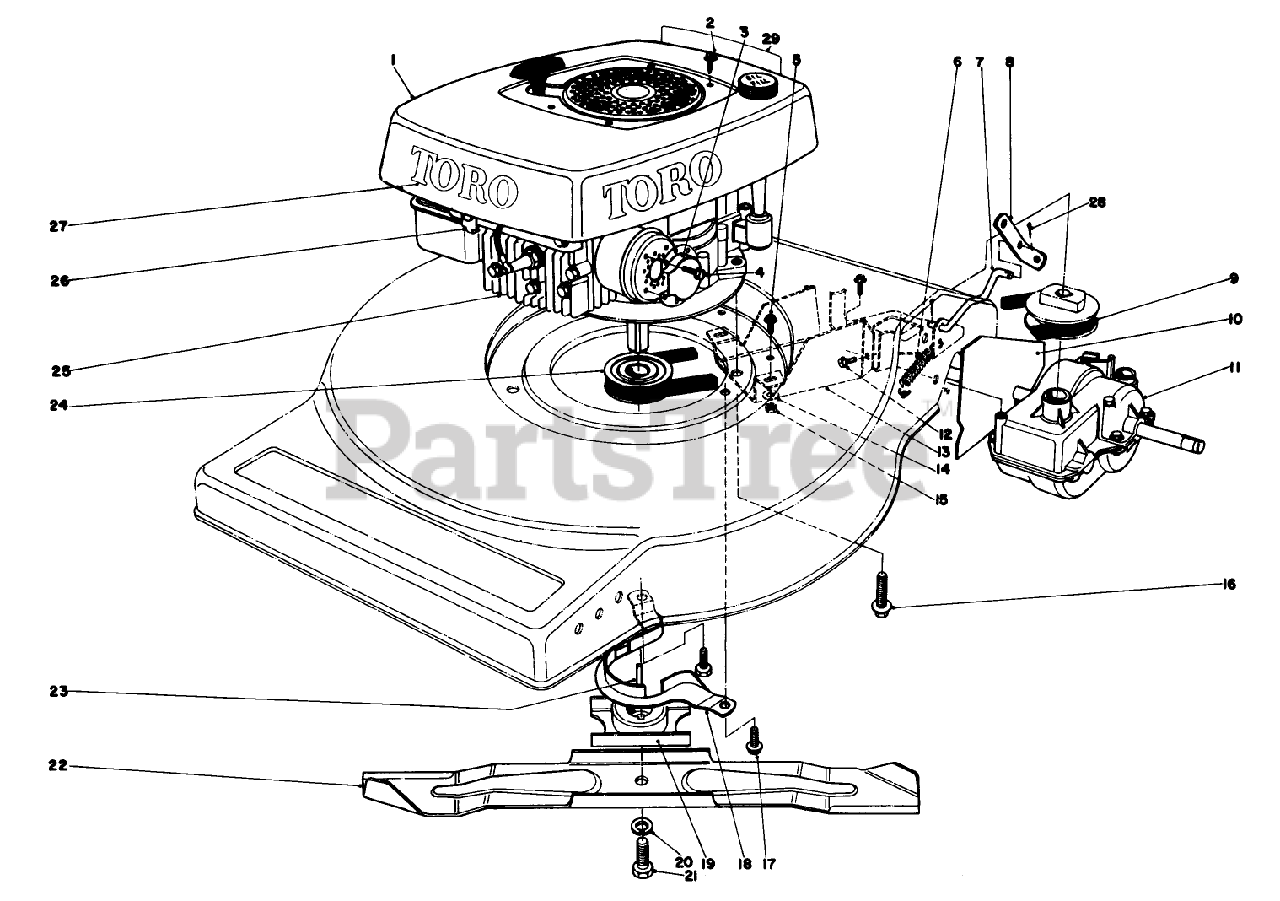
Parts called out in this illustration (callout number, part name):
2	SCREW-THD FORM, HWH
5	SCREW-HWH
6	IDLER SPRING
12	SCREW-HWHTF
14	WASHER-FLAT
20	WASHER-LOCK
23	KEY-SQUARE
25	Engine
27	Decal-TORO
28	PIN-COTTER
29	Decal-Maintenance
